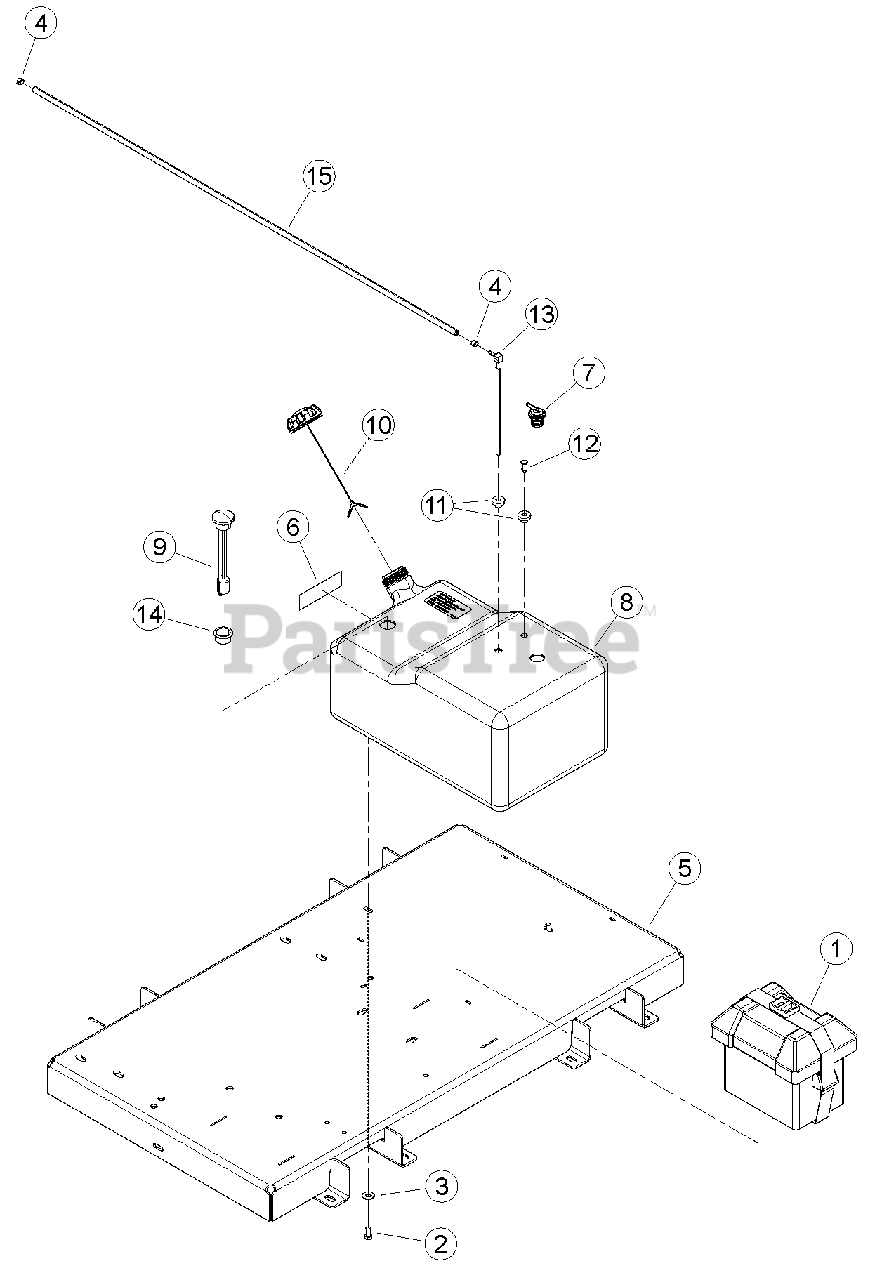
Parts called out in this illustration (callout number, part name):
1	BOX, SMALL BATTERY
2	BOLT, 3/8 X 3/4 GR5 HEX CAPSCREW ZP
3	WASHER, 3/8" FLAT ZP
4	CLAMP, 15/32 SPRING
5	WELDMENT, BASE DL12653
6	DECAL, UNLEADED GASOLINE
7	VALVE, ROLL OVER
8	TANK, ROTOMOLDED FUEL
9	GAUGE, FUEL LEVEL KELCH 100
10	CAP, NON-VENTED EPA/CARB APPROVED
11	GROMMET, TANK FITTING
12	PLUG, TANK VENT
13	FITTING, TANK FUEL PICK-UP TUBE
14	GROMMET, KELCH 100 GAUGE
15	HOSE, 49 INCH FUEL LINE
